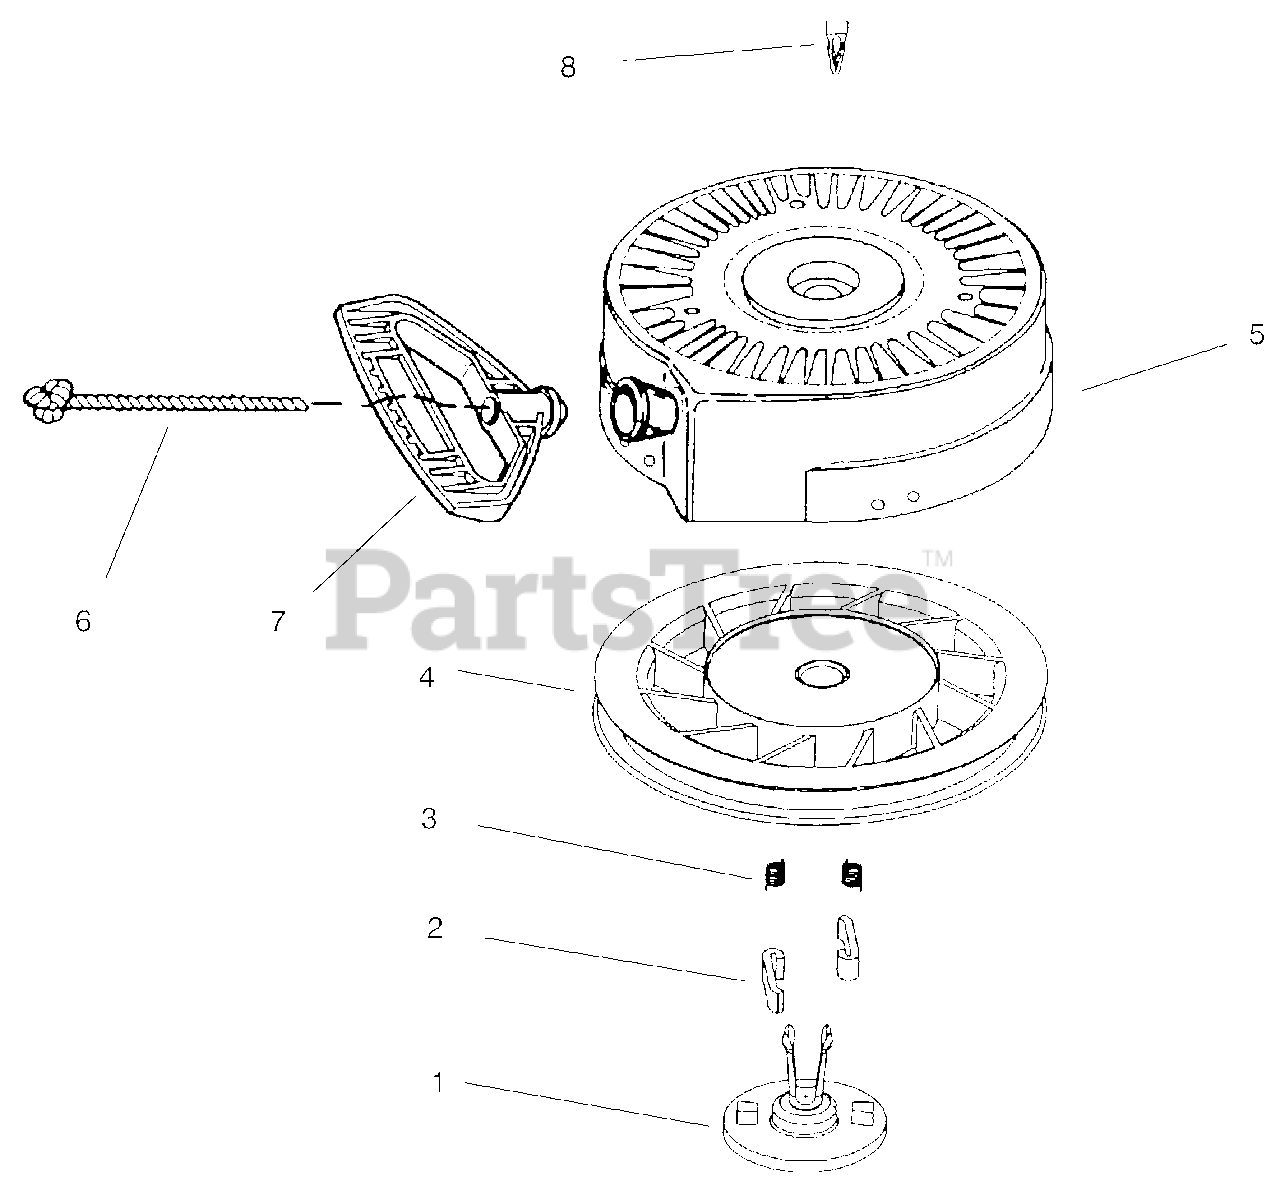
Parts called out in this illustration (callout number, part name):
1	Retainer
2	Starter Dog
3	Dog Spring
4	Pulley & Rewind Spring Asm.
5	Starter Housing Asm.
6	Starter Rope
7	Mitten Grip Handle
8	Locking Tab
